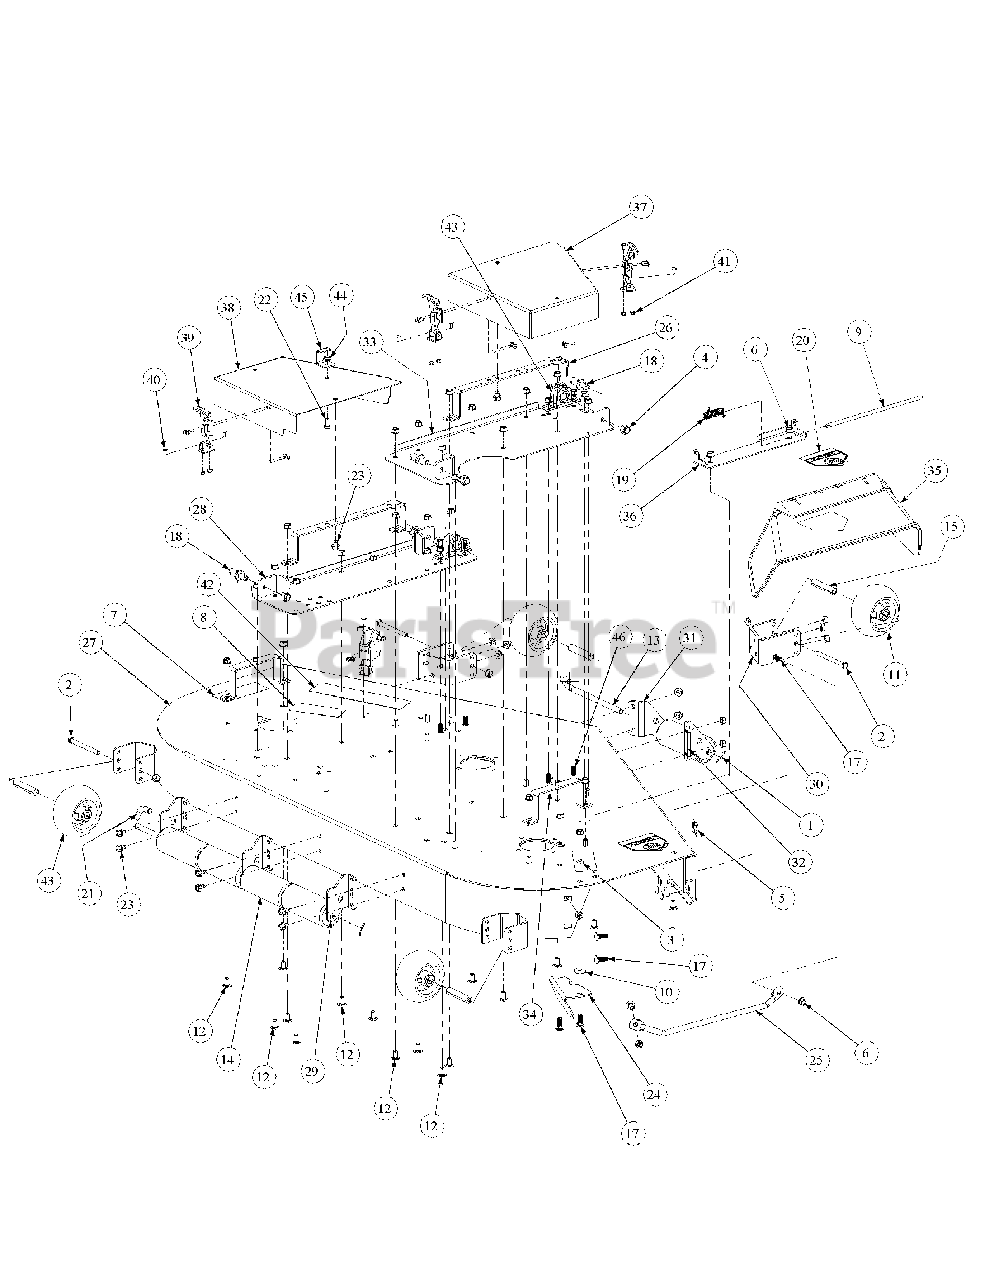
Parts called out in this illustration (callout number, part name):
1	Cotter Pin, .125 Dia. x 1.0
2	Hex Cap Screw, 3/8-16, 3.75
3	Flat Washer, 3/8
4	Lock Nut, Nylon Insert, 1/2-13
5	Label, 60"
6	Flange Lock Hex Nut, 3/8-16
7	Decal, Rotating Blade
8	Decal, Warning Shield Missing
9	Chute Deflector Rod
10	Idler Washer
11	Complete Wheel, 5.00 Dia.
12	Carriage Bolt, 3/8-16 x .75 Lg.
13	Roller Pin, 1/2 Dia. x 7.31 Lg.
14	Front Roller
15	Wheel Spacer
17	Carriage Bolt, 3/8-16 x 1
18	Pin, 5/8 Dia. x 1.2 Lg.
19	Torsion Spring, 0.4ID x 2.16Lg
20	Decal, Danger Hand and Feet
21	Roller Pin
22	Hex Cap Screw, 5/16-18 x .75
23	Hex Index Washer Screw, 3/8-16, .5
24	Chute Bracket
25	Finger Guard
26	Belt Cover Support
27	60" Deck Assembly
28	Left Hand Mount Deck Bracket Assembly
29	Deck Roller Mount Bracket
30	Anti-Scalp Wheel Front Mount Bracket
33	Right Hand Deck Bracket Assembly
34	Outer Belt Cover Support Assembly
35	Chute Deflector
36	Chute Deflector Bracket
37	Right Hand Deck Belt Cover Weldment
38	Left Hand Deck Belt Cover Weldment
39	T-Handle Latch Draw
40	Phillips Head Screw, 10-32
41	Lock Nut, Nylon Insert, 10-32
42	Commercial Mower Label
43	Pillow Block
44	Nut, 5/16-18, Hex Flange Lock
45	Stop Bracket
46	Carriage Screw, 3/8-16 x 1.25
